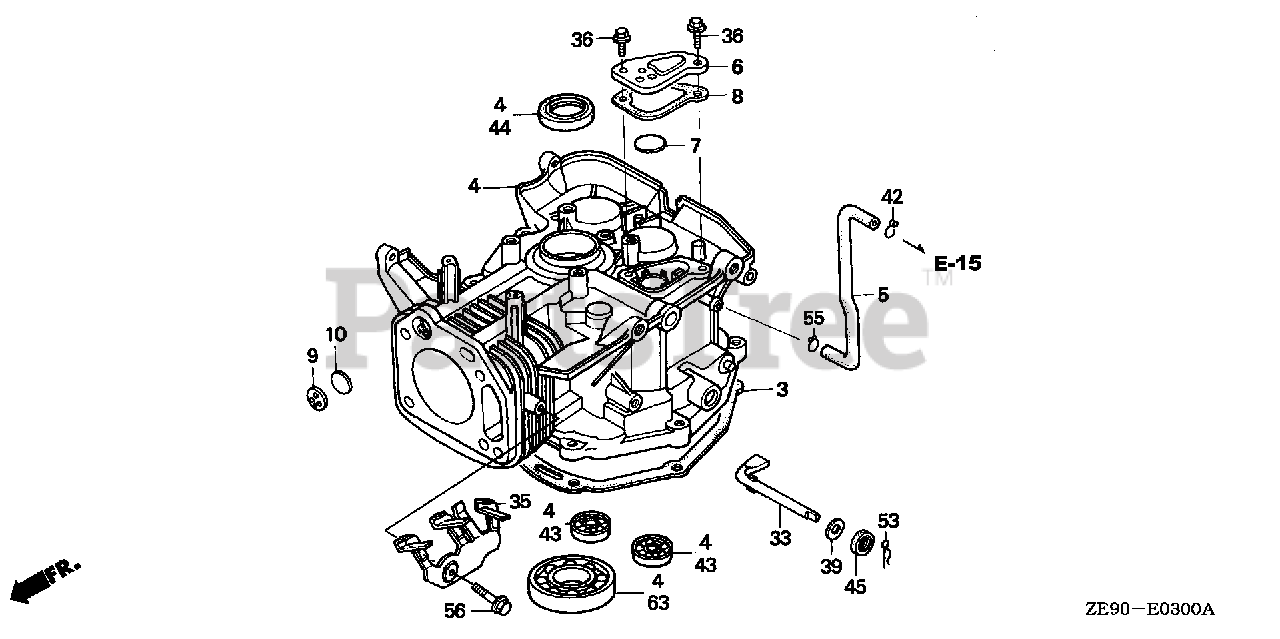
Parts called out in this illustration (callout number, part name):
3	GASKET, OIL PAN
4	CYLINDER ASSY.
5	TUBE, BREATHER (NOT AVAILABLE)
6	CAP, BREATHER CHAMBER
7	VALVE, BREATHER
8	GASKET, BREATHER CAP
9	PLATE, ONE-WAY VALVE
10	VALVE, ONE-WAY
33	SHAFT, GOVERNOR ARM
35	STAY, SWITCH WIRE CLAMP (NOT AVAILABLE)
36	BOLT, FLANGE (6X12) (CT200)
39	WASHER, THRUST (8.1MM)
42	CLIP, TUBE (C11)
43	BEARING, RADIAL BALL (6202)
44	OIL SEAL (35X52X8)
45	OIL SEAL (8X14X5)
53	PIN, LOCK (8MM)
55	CLIP, TUBE (C11)
56	BOLT, FLANGE (6X12)
